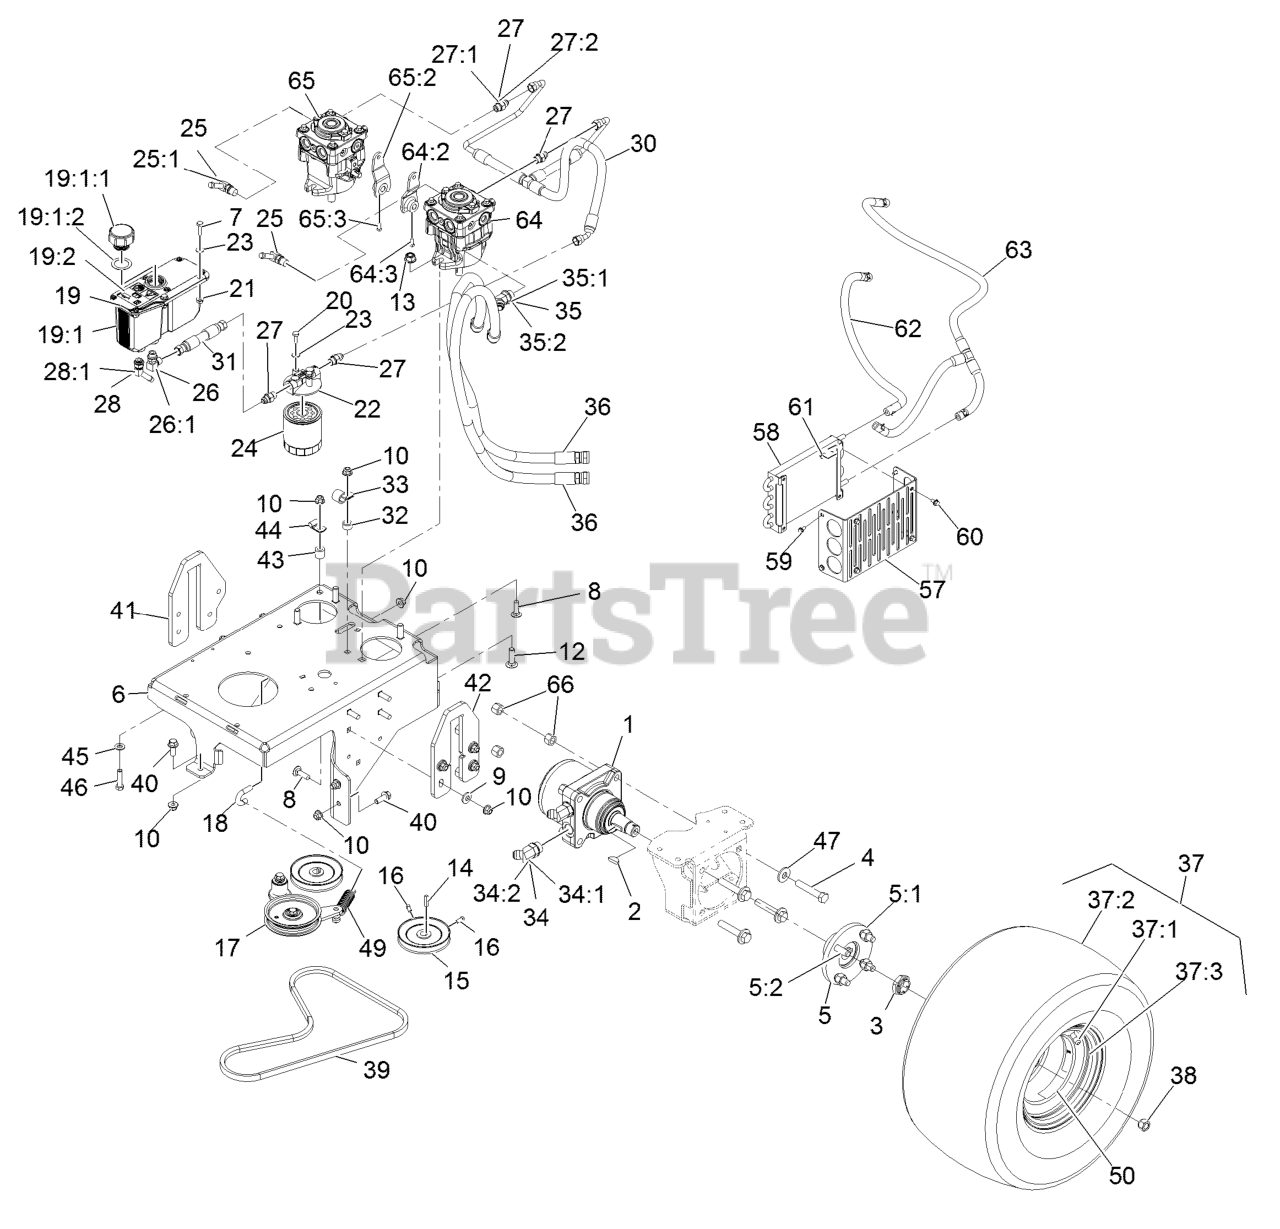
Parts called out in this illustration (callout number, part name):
1	MOTOR-WHEEL
2	KEY-WOODRUFF
3	LOCKNUT
4	SCREW-HH
5	WHEEL HUB / STUD ASM
5:1	HUB-WHEEL
5:2	STUD-TYPE, DRIVE
6	WELDMENT, FRAME
7	SCREW-HH
8	BOLT-CARR
9	WASHER-BELLEVILLE
10	NUT-HF, NI
12	SCREW-HH
13	NUT-HF, NI
15	PULLEY-PUMP
16	SCREW-SET
17	PUMP IDLER ASM
18	ANCHOR, SPRING
19	RESERVOIR ASM
19:1	Reservoir-HYD
19:1:1	Cap-Reservoir, HYD
19:1:2	GASKET-CAP
19:2	DECAL-WARNING
20	SCREW-HH
21	NUT-HHF
22	HEAD-FILTER
23	WASHER-FLAT
24	FILTER-25 MICRON, BI-DIRE
25	FITTING-ELBOW, 90
25:1	O-RING
26	FITTING-ELBOW, 90 DEG
27	FITTING-STRAIGHT
28	FITTING-BARBED, 45 DEG
28:1	O-RING
30	HOSE ASSEMBLY - CHARGE
31	HYD HOSE ASM
32	SPACER-WHEEL
33	CLIP-LOOM
34	FITTING-HYD, 45 DEG
35	FITTING-HYD, 45 DEG
36	HYD HOSE ASM
37	WHEEL/TIRE ASM
37:1	RIM-8 INCH
37:3	Stem-Valve
38	NUT-LUG
39	BELT-V, LOWER PTO
40	SCREW-HHF 3/8-16 X 1
41	PLATE-LIFT, RH
42	PLATE, LIFT LH
44	CLIP-TUBE
45	WASHER-FLAT
46	SCREW-HH
47	WASHER-SPRING
49	SPRING-EXTENSION
50	DECAL-TORQUE, WHEEL HUB LUG
57	BRACKET, COOLER MOUNTING
59	SCREW-HWH
60	SCREW-HHF
61	NUT-KEPS
62	HOSE, HYDRAULIC ASSY
63	HOSE ASM-HYD LP 3/8
64	PUMP W/ARM - LEFT
64:2	ARM-HYDRO
64:3	SCREW-SET
65	PUMP W/ARM -RIGHT
65:2	ARM-HYDRO
65:3	SCREW-SET
66	NUT-LOCK, NI
